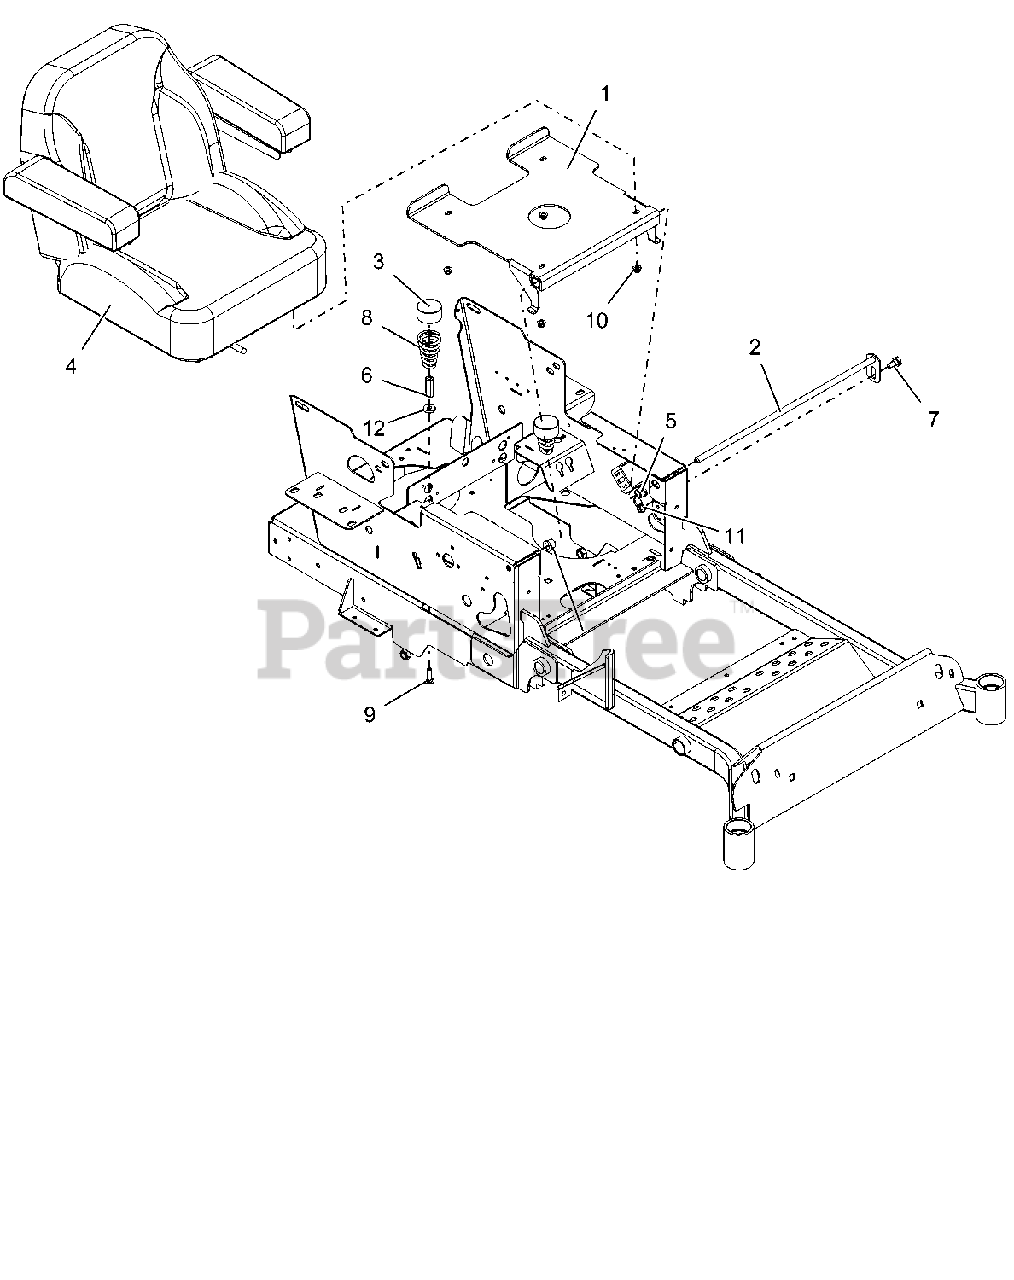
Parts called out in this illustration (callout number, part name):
1	WLDMT, SEAT PLATE
2	WMT, SEAT SHAFT
3	HUB CAP
4	SEAT, SK250 COOL GRAY W/ARMS
5	BSHG, FLG .516X.750X.625X.937
6	NUT COUPLING .375-16X1.75
7	BLT,SHLDR EP .38-16X.30 HEX YZ
8	SPRING, SEAT
9	@BLT-RDHDSQNK .38-16X1.25 G5YZ
10	@NUT-LK-NYL-FLG .31-18 YWZC
11	@NUT-SPNLK-FLG .375-16 YWZC
12	WSHR-FL-STL .406X1.00X.188 YWZ
